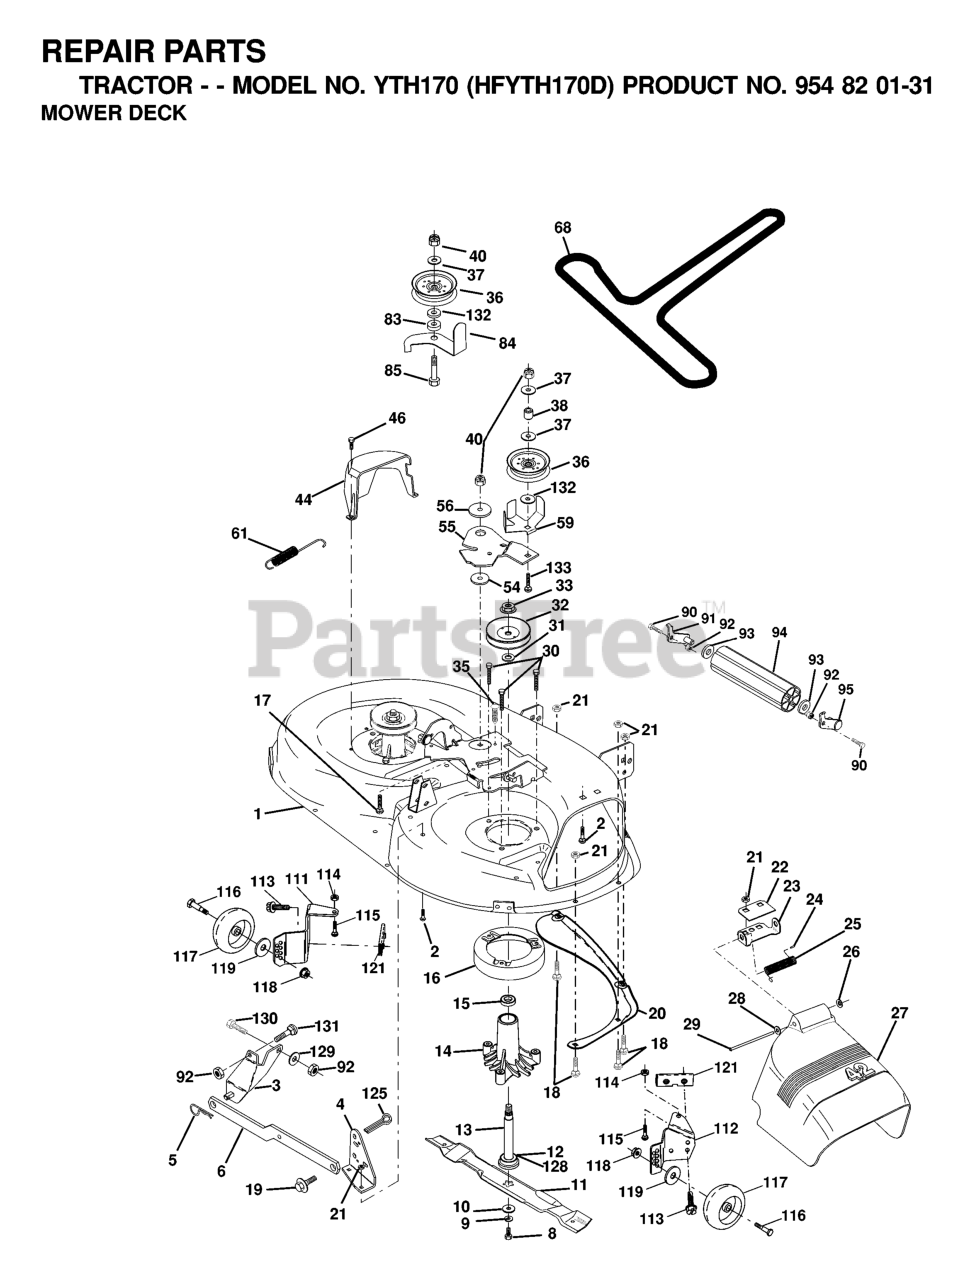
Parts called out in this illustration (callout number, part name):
1	DECK 42"
2	RP BOLT 5/16-18 X3/4 ZN/YEL GR
3	BRKT ASM SWAY BAR
4	BRKT DECK SW BAR
5	RETAINER-SPRNG RB
6	REAR SUSP ARM
8	BLADE BOLT
9	LOCKWASHER
10	WASHER.BLADE
11	Blade Mower 42" High Perf.
12	BEARING.BALL.#6204.(MANDREL)
13	SHAFT ASM VENT
14	HOUSING.MANDREL.VENTED (MACHD)
16	STRIPPER
17	BOLT CARRIAGE
18	BOLT
19	BOLT SHD 5/16-18
20	BAFFLE.VORTEX
21	LOCKNUT
22	STIFFENER BRACKET
23	DEFLECTOR BRACKET
24	CAP-SLEEVE LT
25	SPRING TORSION
26	NUT PUSH M
27	SHIELD DEFLECTOR
28	Washer 11/32 x 5/8 x 16 Ga SD
29	ROD.HINGE
30	SCREW THDROL ROLLING WASHER HD
31	WASHER
32	PULLEY/MANDREL
33	NUT
35	FASTENER.XMAS.TREE
36	FLAT IDLER PULLEY
37	WASHER
38	IDLER SPRING SPACER
44	GUARD MANDREL LH BLACK
46	SCREW.1/4-20X5/8
54	HARDENED WASHER
55	IDLER ARM
56	SPACER.RETAINER.MOWER
59	GUARD, BELT
61	SPRING EXTENSION
68	V-BELT TRIPATH
84	KEEPER.BELT.IDLER
90	BOLT
91	BRACKET LH (A)
92	NUT
93	Washer 1 17/32 X 7/8 X 16 Ga
94	NOSE ROLLER
95	BRACKET RH (B)
111	BRACKET WHEEL GAUGE LH 42" DK
112	BRACKET WHEEL GAUGE RH 42" DK
113	SCREW 5/16"
114	NUT
115	BOLT.CARR.5/16-18X1/2
116	BOLT M
117	WHEEL.GAUGE.STANDARD
118	LOCKNUT
119	WASHER.5/16.FLAT.STE.STD.
121	BRACKET.EXTRUDED.GAGE.WHEEL
125	Pin Cotter 1/4 x 1 Plated
128	WASHER FELT
129	WASHER
131	BOLT D
132	Washer 13/32 x 1-3/8 x 13 Ga.
